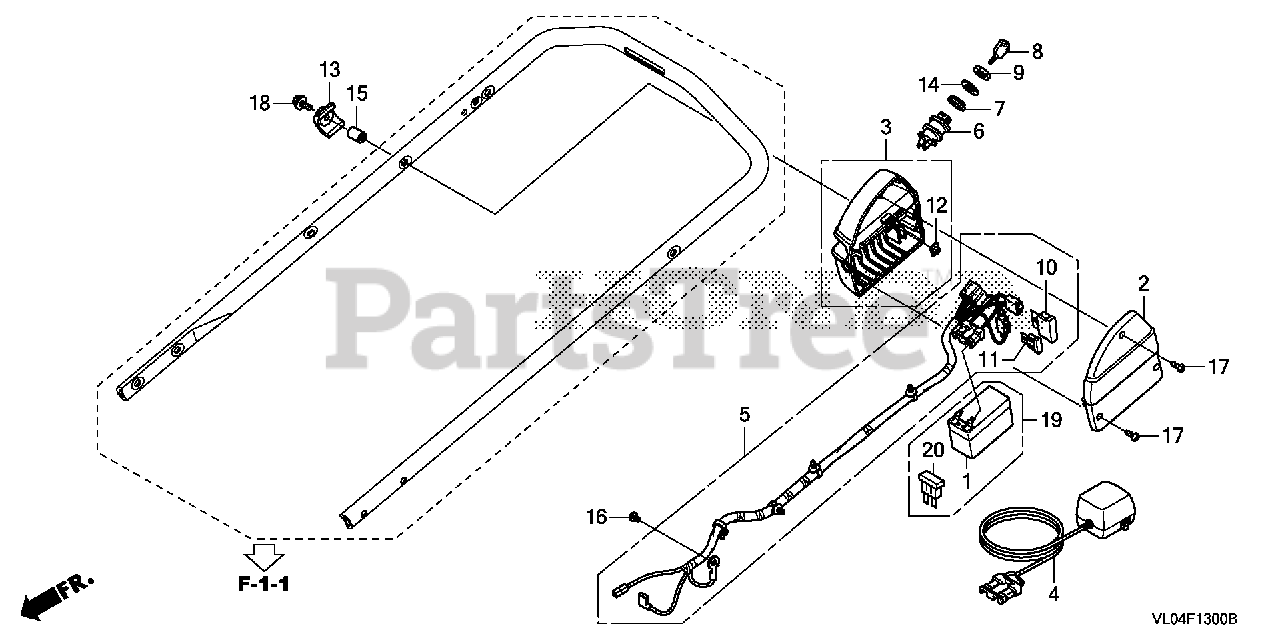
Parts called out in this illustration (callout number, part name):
1	BATTERY KIT (MSDS)
1	BATTERY ASSY. (MSDS)
2	COVER, BATTERY
3	BOX, BATTERY
4	CHARGER ASSY., BATTERY (120V-AC/60HZ)
5	HARNESS ASSY., MAIN
6	SWITCH ASSY., MOMENT
7	BASE, MOMENT SWITCH
9	NUT, SWITCH
10	FUSE A
10	FUSE (30A)
11	FUSE, BLADE (3A)
12	NUT, SPECIAL (6X7)
13	WASHER, FRAME JOINT
14	WASHER, SWITCH
15	COLLAR, BATTERY MOUNTING
16	SCREW, PAN (5X8)
17	SCREW, TAPPING (4X16)
18	BOLT, FLANGE (6X35)
19	BATTERY KIT (MSDS)
20	FUSE, BLADE (30A)
